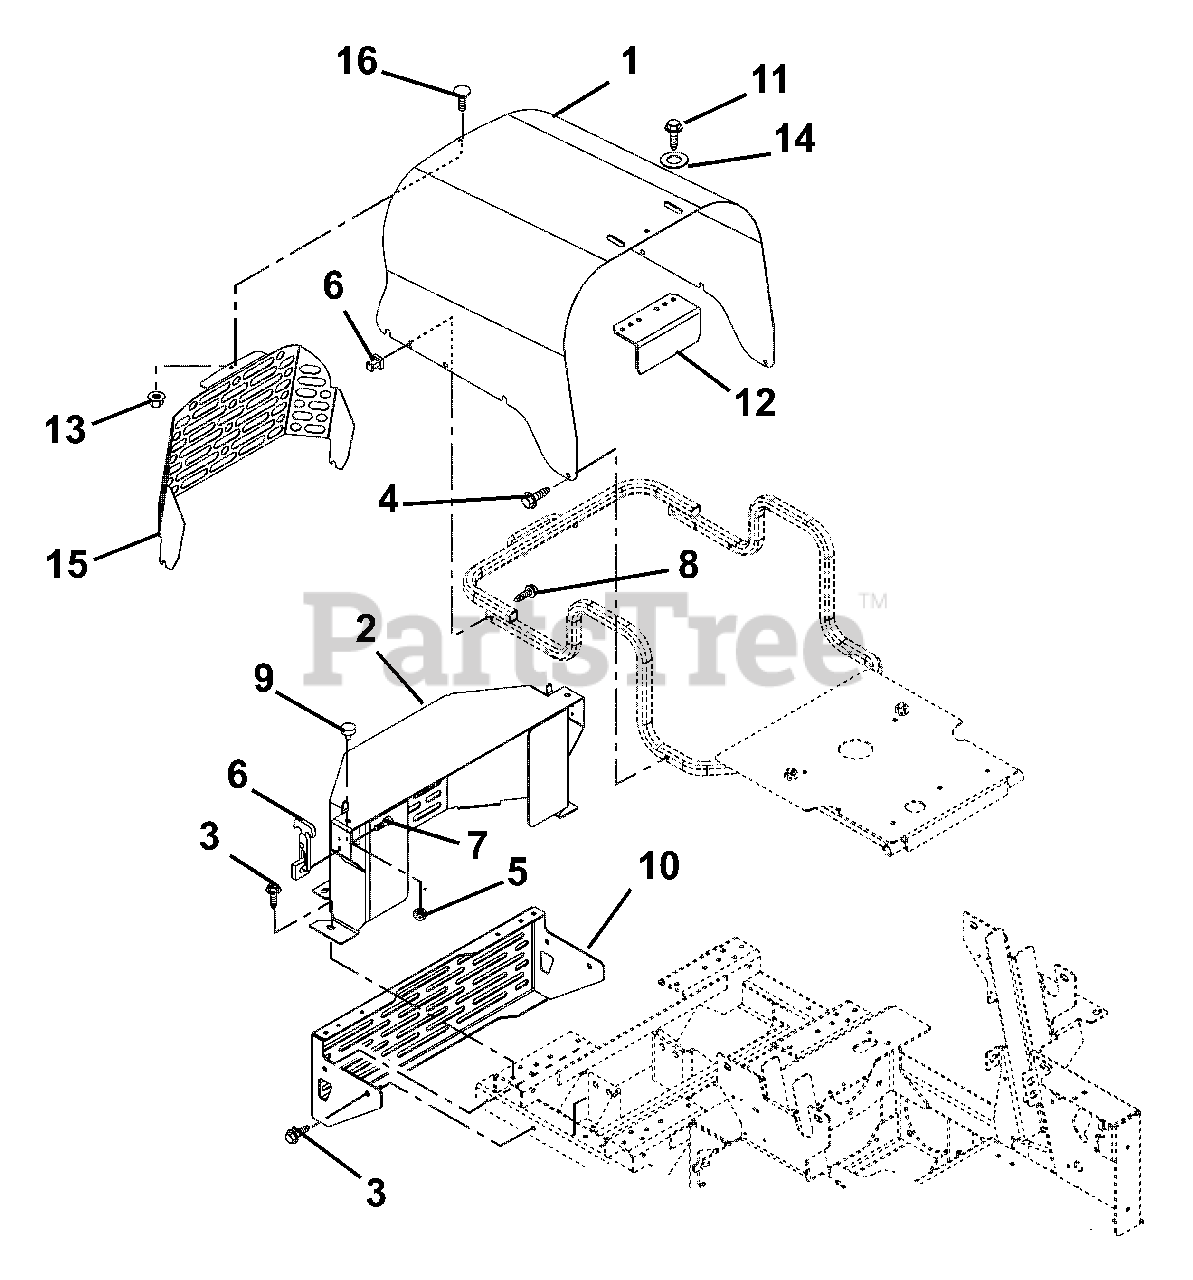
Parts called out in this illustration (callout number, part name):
2	Diesel Belt Guard (075, 076, 318, 319)
2	Weldment, Belt Guard (073, 074)
3	Screw, Tapping .38-16 x .75 Hex Washer Head
4	Screw, Tapping .38-16 x .50 Hex Washer Head
5	Nut, Spin Lock, Flange .312-18
6	Latch, Rubber
7	Screw, Machine 10-24 x .50 Hex Washer Head
8	Screw, Machine 10-24 x 1.50 Hex Washer Head
9	Button, Bumper
10	Bumper, Rear
11	Screw, Tapping .25-20 x .50 Hex Washer Head
12	Guard, Radiator Cap
13	Nut, Locking Top Flange .25-20
14	Washer, Flat Steel .281 x .62 x .065
15	Guard, Hood
16	Bolt, Round Head Square Neck .25-20 x .50 Grade 5
